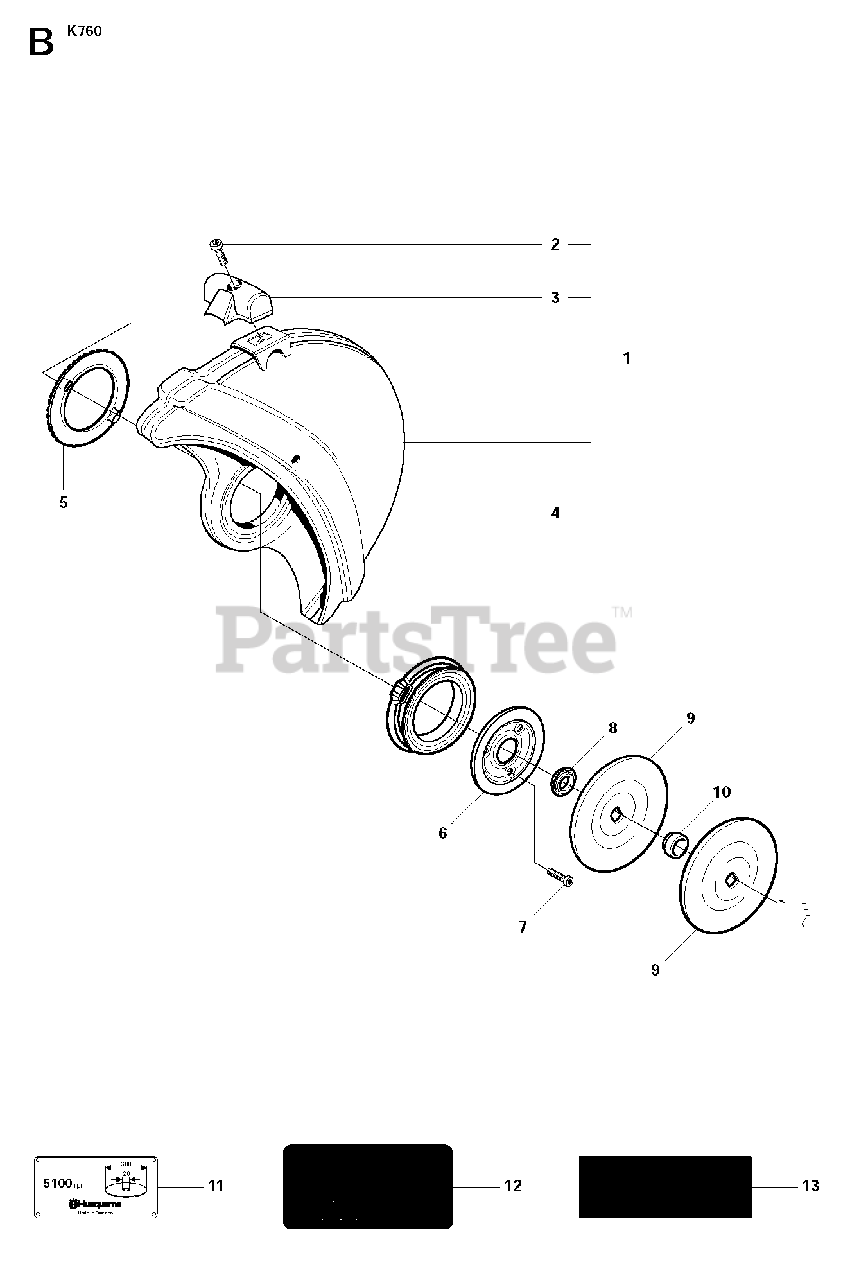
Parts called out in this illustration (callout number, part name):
1	BLADE GUARD"12"", Incl. 2 - 4"
1	BLADE GUARD"14"", Incl. 2 - 4"
2	SCREW ITXSCM
7	SCREW ITXSCM
8	SUPPORT FLANGE
9	FLANGE WASHERDiam 105 mm
9	FLANGE WASHERDiam 119 mm
10	KITDiam 20 mm
10	KITDiam 22,2 mm
10	KITDiam 25,4 mm
10	BUSHINGDiam 30,5 mm
11	LABEL"12"", Diam 1"""
11	LABEL"12"", Diam 20 mm"
11	LABEL"14"", Diam 1"""
11	LABEL"14"", Diam 20 mm"
